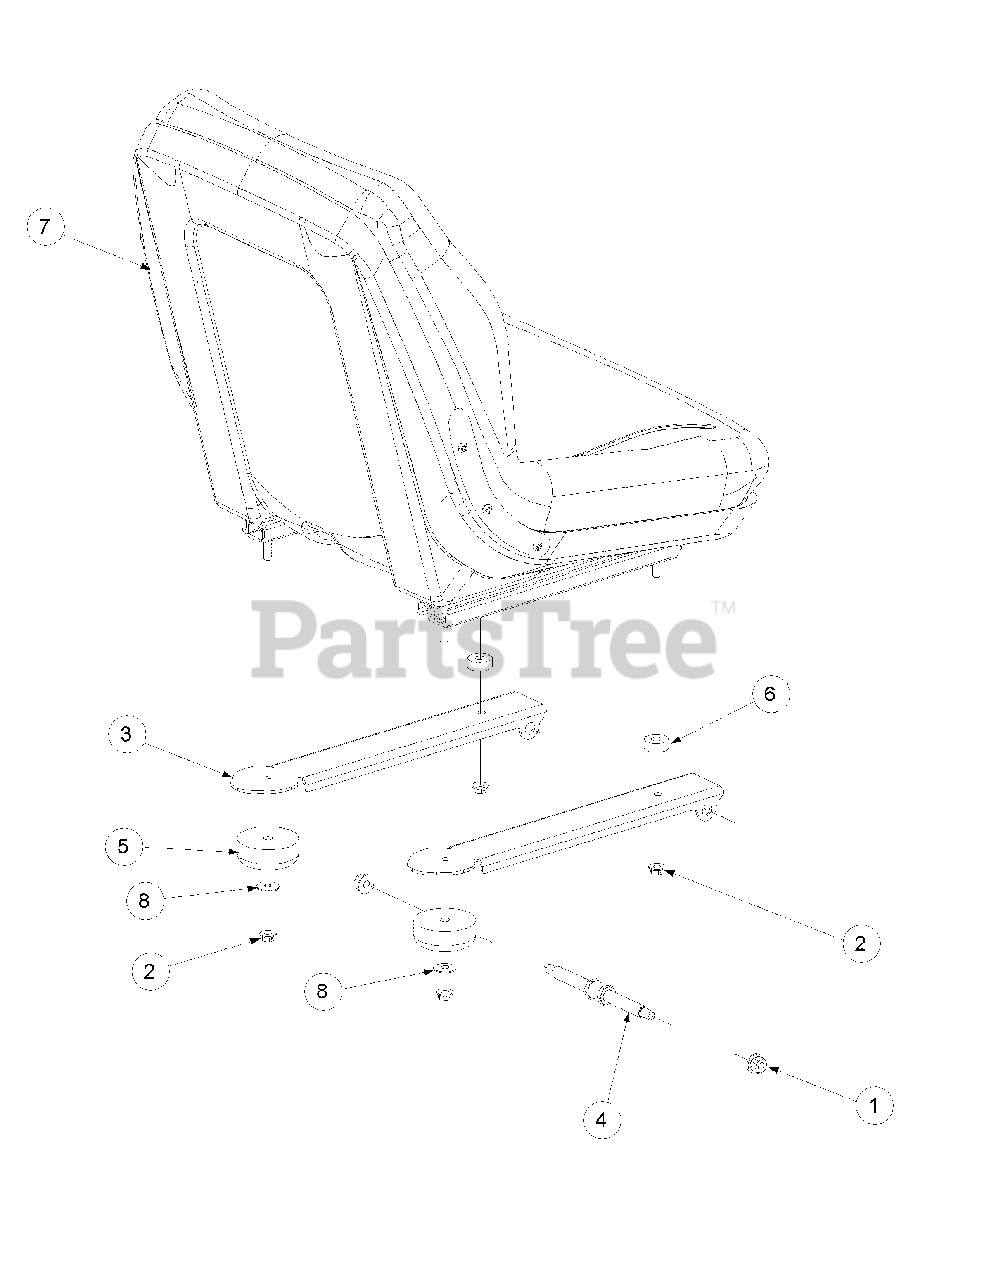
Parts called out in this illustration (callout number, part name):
1	Nut, Hex 3/8-16 Flange Lock
2	Lock Nut, Hex Flange, 5/16-18
3	Mounting Bracket, Seat
4	Shoulder Screw, .50x2.345, 3/8-16
5	Grommet, 2.5 OD x 1.0 Long
6	Spacer, .406 ID x 1.00 OD x .38
7	Adjustable Seat, Black
7	Armrest Kit
7	Screw, Button Head 1/4-20 x .50
8	Flat Washer, .406 ID, 1.00 OD, .105
